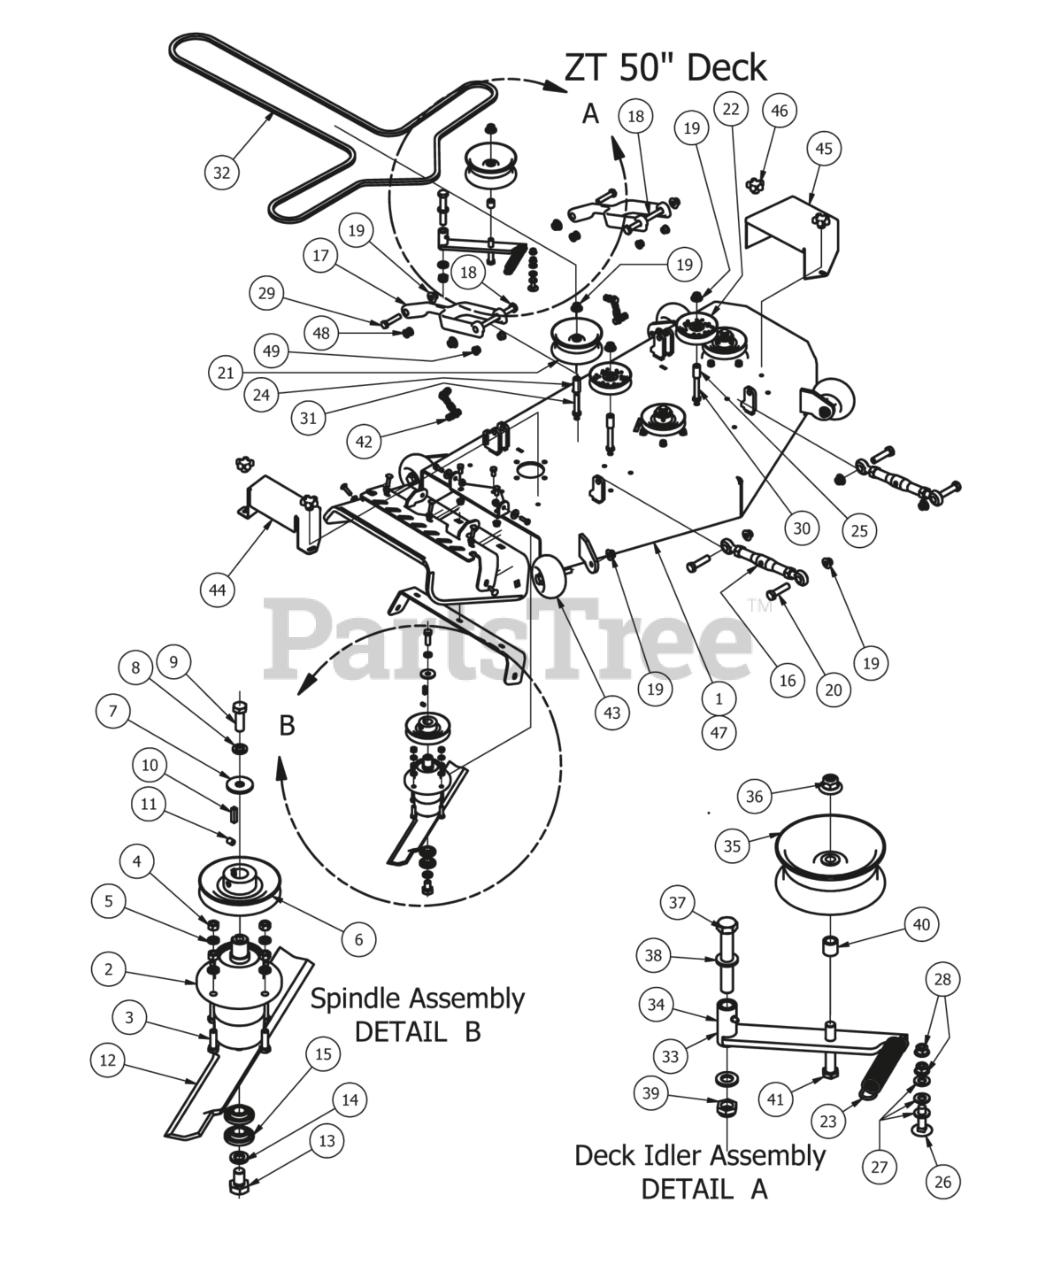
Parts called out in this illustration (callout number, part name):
1	50" Deck Only
2	Spindle - Aluminum - 2012 ZT
3	3/8" x 1 1/4" Hex Bolt
4	3/8" Hex Nut
5	3/8" Lock Washer
6	5" Deck Pulley
7	1/2 Belleville Washer
8	1/2" Lock Washer
9	1/2"-20 x 1 1/2 - Grade 5 Fine Thread Bolt
10	1/4" x 1" Key
11	3/8" Set Screw
12	50 Inch Fusion Blade
13	5/8" x 1 1/2" Grade 8 Bolt
14	5/8" Lock Washer
15	Spindle Bearing
16	Turnbuckle (Top Link)
17	Deck Arm Assembly
18	1/2" x 5 1/2" Bolt
19	1/2-13 Nylon Flange Nut-Orange
20	5/8" x 2 1/2" Hex Bolt
21	5 3/4" Deck Idler Pulley
22	4-3/4 Idler Pulley
23	Deck Idler Spring
24	1 3/4" Pulley Spacer
25	Pup Pulley Spacer
26	3/8 x 1-1/2 Carriage Bolt
27	3/8" Flat Washer
28	3/8" Nylock Flange Nut
29	1/2-13X 2-1/4 GR Hex Bolts
30	1/2 x 3 1/2 Flange Bolt Grade 8
31	1/2" x 4" Bolt (Grade 8)
32	50" Deck Belt
33	Deck Idler Assembly Components 34,35,36,40,41
34	Deck Idler Bracket
35	5 3/4" Deck Idler Pulley
36	1/2-13 Nylon Flange Nut-Orange
37	5/8" x 4" Hex Bolt
38	.635 ID Plastic Washer
39	5/8" Nylock (1/2 Jam)
40	3/4 OD x 1/2 ID x 3\4 Length
41	1/2-13 x GR 5 Hex Bolt Zinc
42	Chain assembly
43	Deck Wheel
44	1/2 Metal Spindle Cover
45	Pulley Cover
46	5/16" Knob
47	50" ZT Deck - Completed Assembly
48	Flange for Lower Deck Arm
49	Flange Bushing For Deck Arm upper
